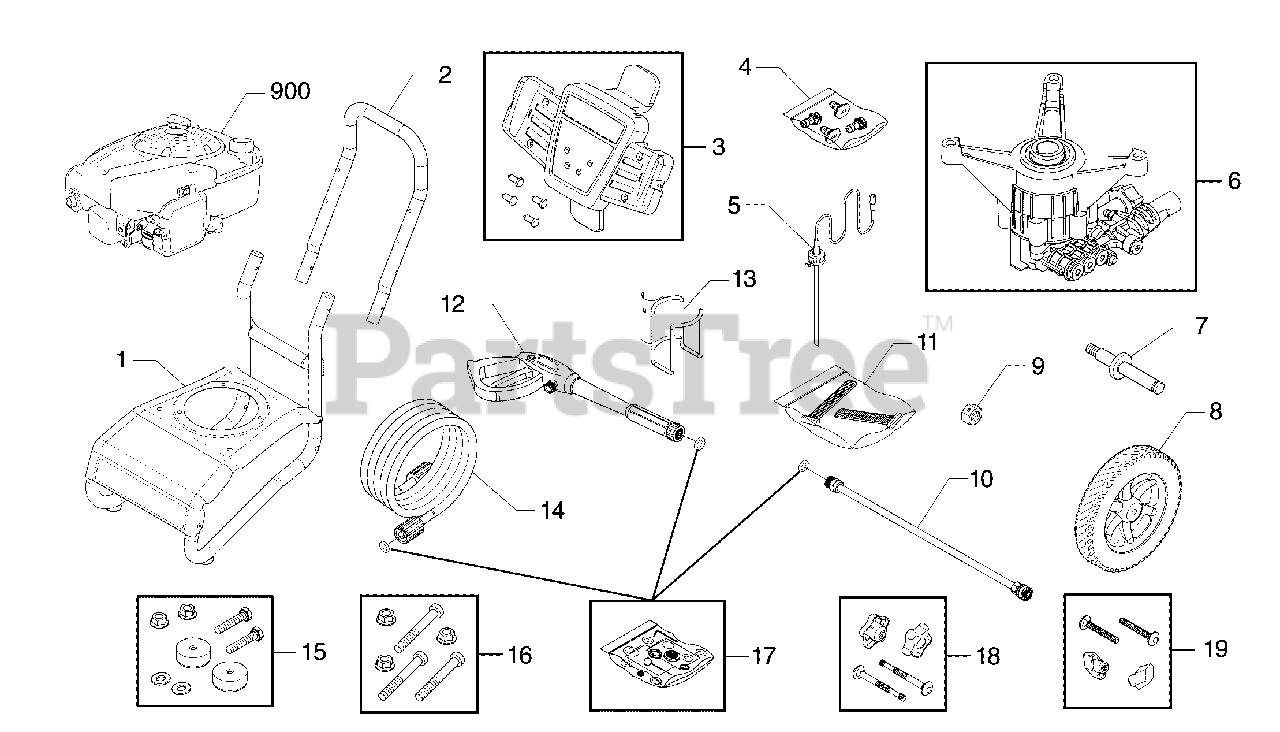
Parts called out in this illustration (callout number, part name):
4	KIT, QC Nozzle
10	EXTENSION, QC
12	GUN
14	HOSE
15	MOUNT, Vibration
16	KIT, Hardware, Pump Mounting
